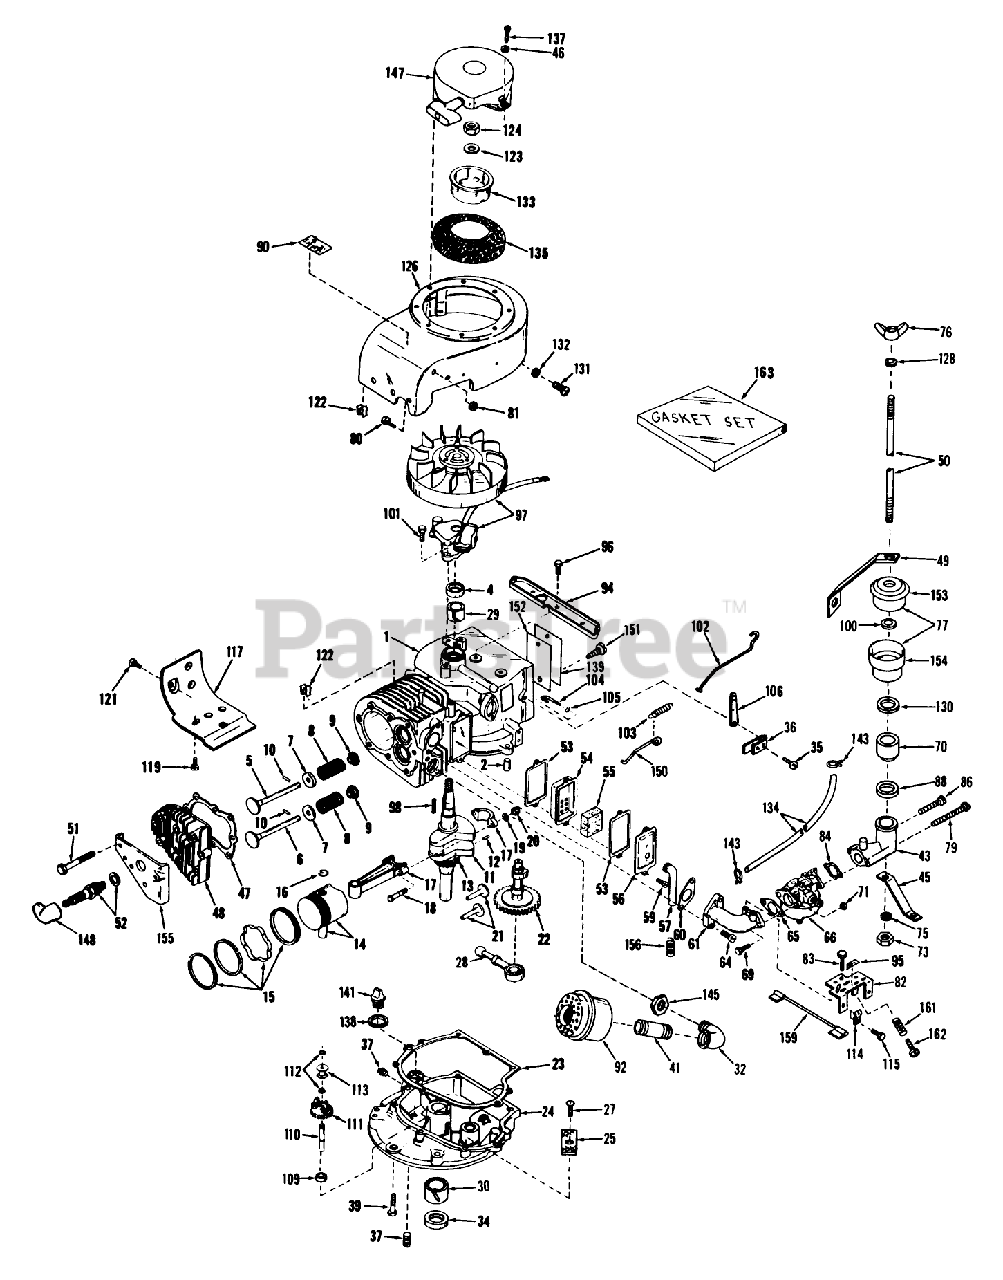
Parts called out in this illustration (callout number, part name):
1	Cylinder Assy. (Incl. Ref. Nos.2,4 29)
2	Pin-Dowel
4	Seal, Oil
5	Valve, Intake (Standard)
5	Valve, Intake (1/32" oversize)(Incl. Ref. No.9)
6	Valve, Exhaust (Standard)
6	Valve, Exhaust (1/32" overs.)(Incl. Ref. No.9)
7	Cap-Spring, Valve
8	Spring-Valve
9	Cap, Lower valve spring
9	Cap, Lower Valve Spring (1/32" oversize)
10	Pin, Valve spring retaining
11	Crankshaft Assy. (Incl. Ref. Nos.12 13) V40-50008E
11	Crankshaft Assy. (Incl. Ref. Nos.12 13) V40-50037E
12	Pin, Groove
13	Gear-Crankshaft
14	Piston Pin Assy. (Standard)(Incl. (2) of Ref. No.16)
14	Piston Pin Assy. (.0101 oversize)(Incl. (2) of No.16)
14	Piston Pin Assy. (.0201 oversize)(Incl. (2) of No.16)
15	Ring Set, Piston (Standard)
15	Ring Set, Piston (.010 overs.)
15	Ring Set, Piston (.020 overs.)
17	Rod Assy., Connecting (Incl. Nos.18,19 20)
18	Bolt, Connecting Rod
19	Washer
21	Lifter Valve
22	Camshaft
23	Gasket-Cover, Cylinder
24	B Flange Assy., Mounting (Incl. Nos.25, 27, 34, 43 110)
25	Screen-Oil Filter
27	Screw
28	Pump, Oil
29	Bushing, Crankshaft
30	Bushing, Crankshaft
32	Elbow, Exhaust (90 degree)
34	Seal-Oil
35	Screw
36	Clamp-Lever, Governor
37	Plug-Drain, Oil (SQH 1/4-18)
39	Screw (1/4-20 x 1-1/4)
41	Nipple, Pipe
43	Elbow, Air cleaner
45	Brace, Cleaner elbow
46	Washer
47	Gasket-Head, Cylinder
48	CYLINDER HEAD
49	Brace Cleaner
50	Stud, Air cleaner
51	Screw
52	SPARK PLUG
53	Gasket-Breather
54	Body-Breather
55	Element-Breather
56	Cover-Valve
57	Tube-Breather
59	Screw
60	Gasket-Intake
61	Pipe, Intake
64	Screw (T-30, 5/16-18x1-3/32)
65	Gasket
66	Carburetor
70	Spacer, Cleaner
71	Nut and Lock Washer (1/4-28)
75	Lockwasher, Split
76	Nut-Wing
77	Cleaner Assy., Oil Bath Air (Incl. Nos.100,128,130,153 154)
79	Screw
80	Screw
81	Nut-Jam (5/16-24)
82	Control Assy., Speed
83	Screw (10-24 x 9/16)
84	Gasket
86	KIT - SEAL WIPER
88	Gasket, Spacer
90	Decal, H.P.
92	Muffler
94	Bracket, Blower Housing (Incl. Nos. 131)
95	Decal
96	Screw (1/4-20x19/32)
97	Magneto
98	Key, Flywheel
100	O Ring
101	Screw
102	Link Governor
103	Spring Governor
104	Rod, Governor (Incl. Nos. 146)
105	Washer-Flat
106	Lever-Governor
109	Spacer
110	Shaft, Governor
111	Governor Gear ASM
112	Ring-Retaining
113	Spool-Governor
114	Conduit
115	Screw (10-32 x 3/8)
117	Emnsion, Blower Housing
119	Screw
121	Screw
122	51004 GIL ROTARY TI
123	Washer
126	Housing, Blower
128	Washer
130	1565F GIL TILLER.AD
131	Screw
132	Lockwasher
133	Cup-Starter
134	Line-Fuel
134	Line, Fuel V40-50037E
135	Screen, Air
137	Screw
138	Gasket
139	480B GIL SNWTHWR O/
141	Plug-Fill, Oil
143	Clamp-Line, Fuel
145	Nut, Conduit
147	Starter, Rewind
148	Cover-Spark Plug
150	Link, Governor spring
151	Stud
152	IDENTIFICATION PLATE
153	Cover, Oil bath cleaner
154	Bowl, Oil Bath Cleaner
155	Cover, Cylinder head
156	Spring, Coil
159	Wire, Ground
161	Spring-Compression
162	Screw
163	Gasket Set
